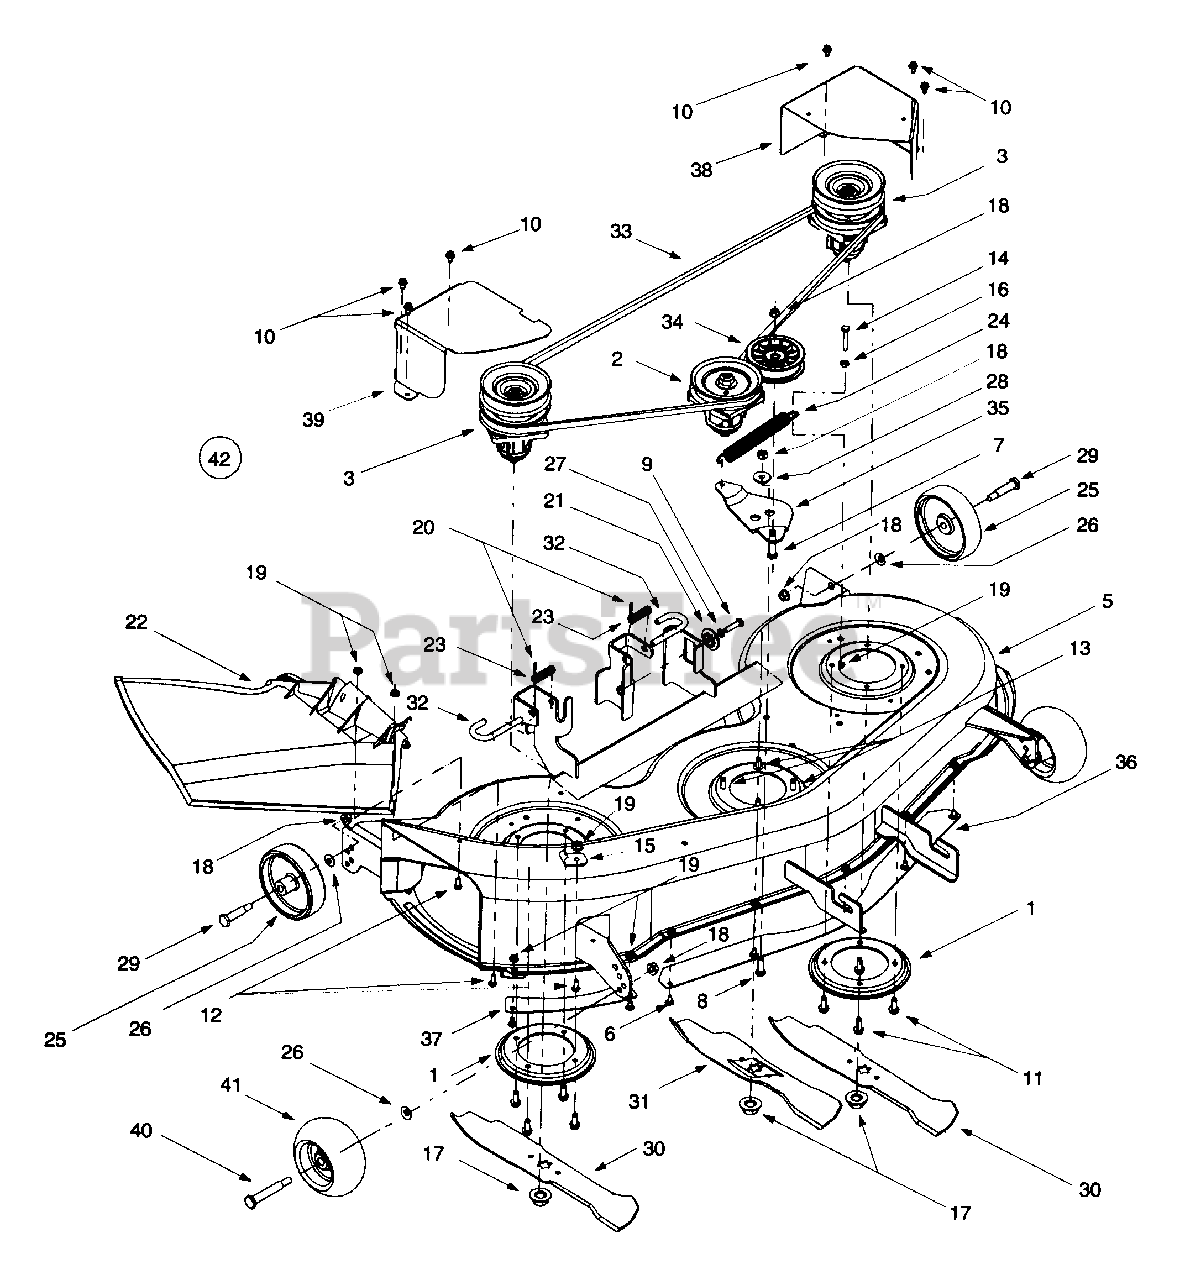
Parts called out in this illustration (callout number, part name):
3	Double Pulley Spindle Assembly
5	46-inch Deck Shell
6	Carriage Screw, 1/4-20 x .5
7	Hex Cap Screw, 3/8-16 x 1.75
8	Hex Cap Screw, 3/8-16 x 1.0
9	Hex Cap Screw, 5/16-18 x 1.25
10	Self Tapping Screw, 1/4-20 x .5
11	Self Tapping Screw, 5/16-18 x .875
12	Hex Cap Screw, 1/4-20 x .62
13	Self Tapping Screw, 5/16-18 x .75
14	Hex Cap Screw, 1/4-20 x 1.25 (Grade 5)
15	Retainer Hook
16	Center Lock Nut, 1/4-20
17	Hex Flange Nut, 5/8-18
18	Flange Lock Nut, 3/8-16
19	Hex Flange Lock Nut, 1/4-20
20	Internal Cotter Pin, .072 x 1.12
21	Deck Adjustment Gear
22	Side Discharge Chute Assembly
23	Compression Spring, .406 x .531 x 1.75
24	Extension Spring, .91 x 7.33
25	Deck Wheel, 5 x 1.38
26	Bell Washer, .401 x .87 x .063
27	Lock Washer, 5/16
28	Shoulder Spacer, .625 x .169
29	Shoulder Spacer, .498 x 1.53
30	Three-in-one Blade, Star Center, 16.28
31	Three-in-one Blade, Star Center, 14.88
32	Deck Release Pin
33	Deck Belt
34	Flat Idler Pulley, 3.5 OD
41	Deck Wheel, 5
